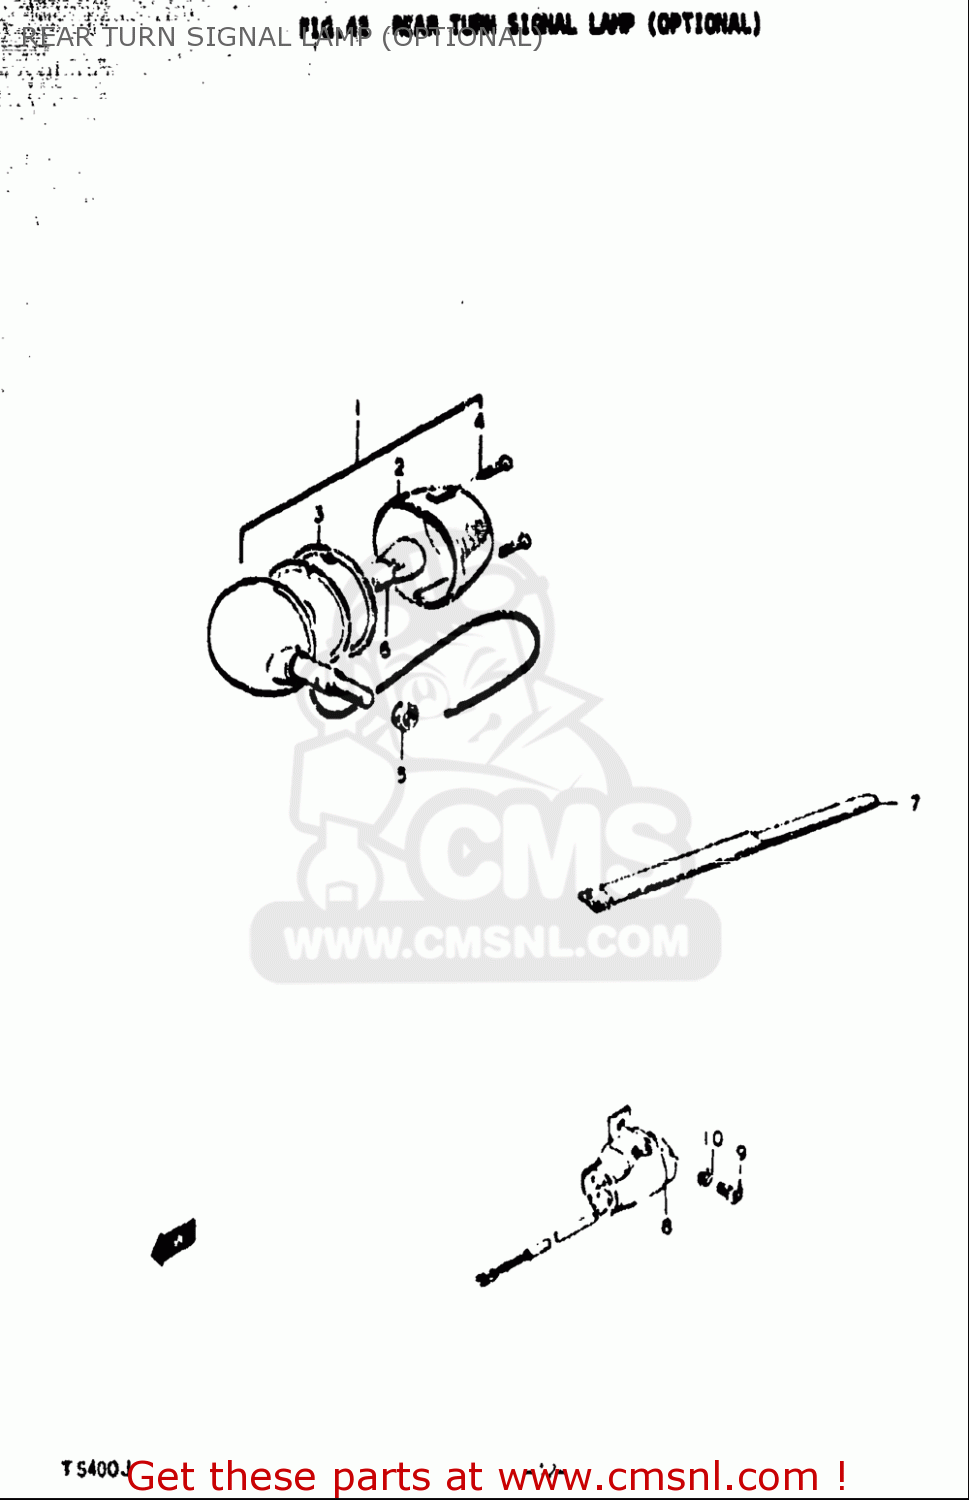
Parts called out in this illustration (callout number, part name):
1	LAMP ASSY,RR TURNSIGNAL
3	GASKET,TURNSIGNAL LENS (NAS)
4	SCREW
5	NUT
6	BULB(12V23W,STANLEY,A4577A)
7	CLAMP
8	RELAY,TURN SIGNAL
9	SCREW
10	WASHER,LOCK
